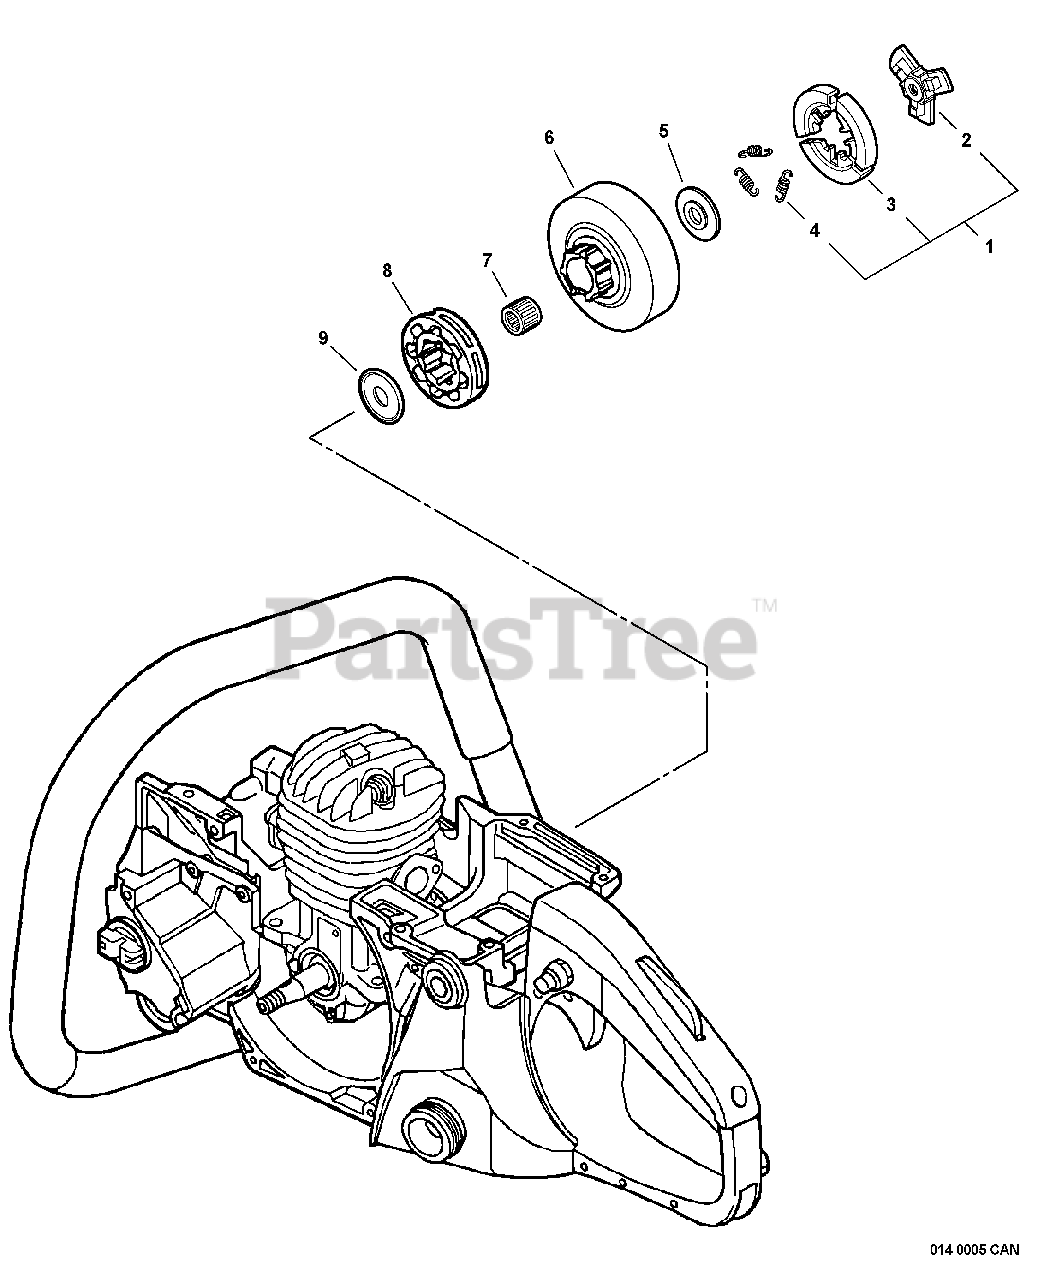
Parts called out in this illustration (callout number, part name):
1	CLUTCH ASSY
2	HUB, CLUTCH
3	CLUTCH SHOE SET
4	SPRING, CLUTCH
5	PLATE, CLUTCH
6	DRUM, CLUTCH
7	BEARING, NEEDLE
8	SPROCKET, RIM
9	PLATE, CLUTCH
